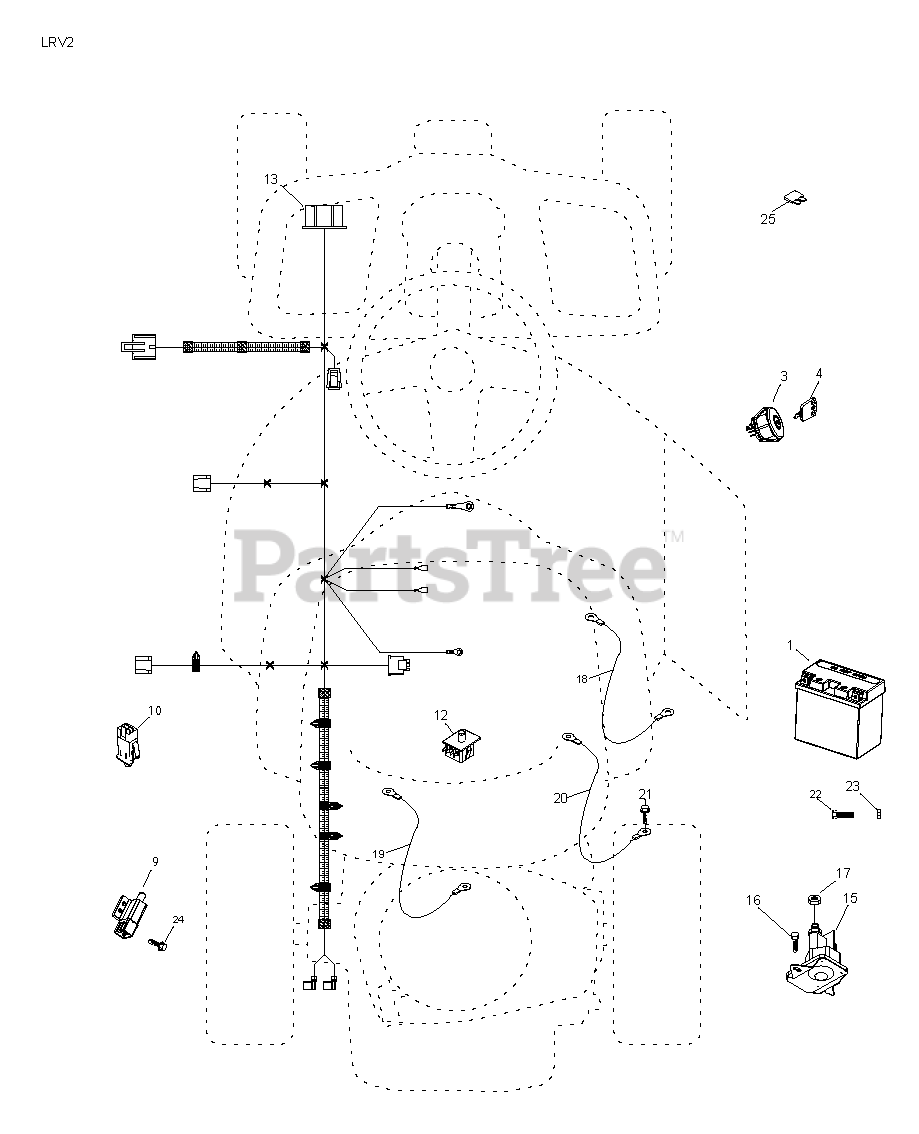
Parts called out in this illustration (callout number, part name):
1	BATTERY.6A.12V.LEOCH
3	SWITCH.IGN.DELTA.W.LGH.ROS
4	KEY.CHAIN.BLISTER.PACK.GEN.USA
9	SWITCH INTERLOCKT
10	SWITCH INTERLOOK PUSH-IN
12	SWITCH.SEAT.DP W/RAMPS
13	HARNESS.IGN.LRVB.ELECSTART
15	SOLENOID.W/BRASS.PLUNGER
16	SCREW
17	NUT
18	CABLE.BATTERY.20.RED.8 AWG
19	CABLE.STARTER.6GA.11"RED
20	CABLE GROUND 6 GA. 12" BLACK
21	SCREW 5/16"
22	SCREW.HEX.M5X0.8.9MM (2 2)
23	NUT.M5.(.393X.275)
24	SCREW.TORX.#10-14X.750
